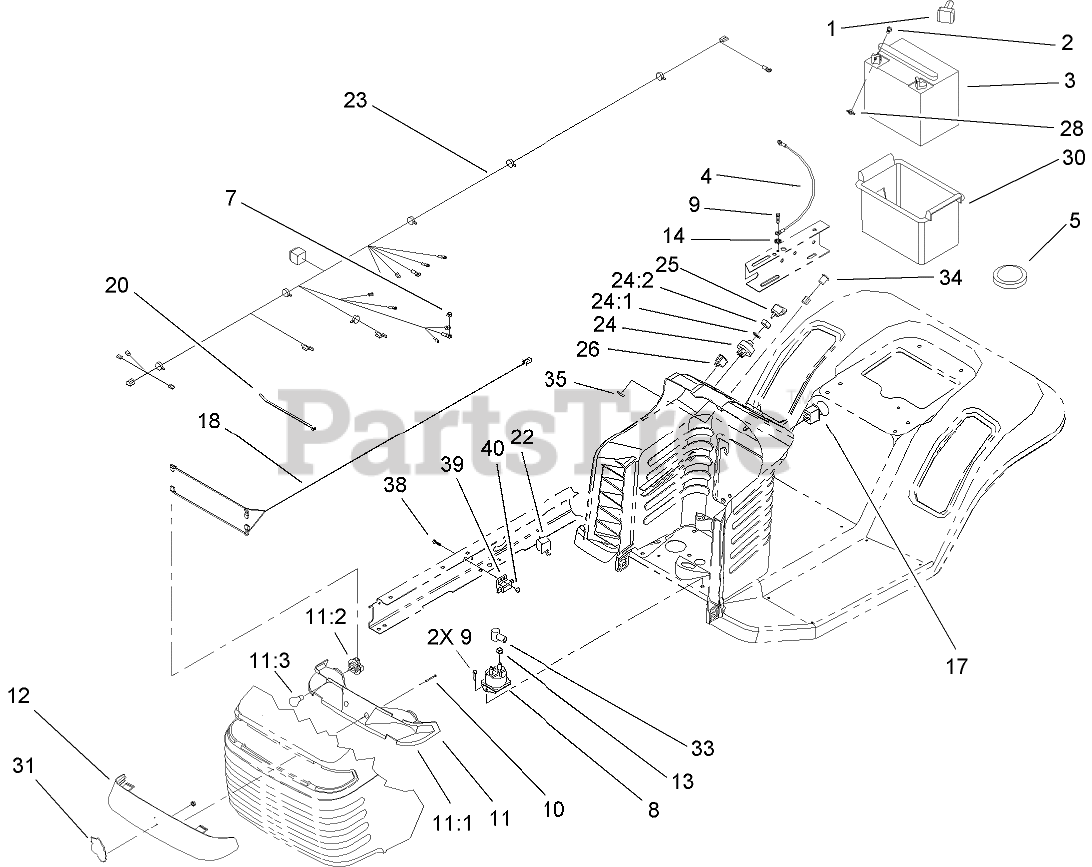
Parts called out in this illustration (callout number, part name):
1	BOOT-TERMINAL
2	SCREW-HH
3	BATTERY-155 CCA
4	WIRE ASM
5	SWITCH-SEAT
7	NUT-KEPS
8	SOLENOID-STARTER
9	SCREW-HWH
11	HEADLIGHT REFLECTOR ASM
11:1	REFLECTOR-LIGHT
11:2	SOCKET-HEADLIGHT
11:3	BULB
12	LENS-HEADLIGHT
13	NUT-KEPS
14	WASHER-LOCK/EXT
17	SWITCH-PTO
18	HARNESS-HEADLIGHT
20	TIE-CABLE
22	RELAY
23	HARNESS-WIRE
24	Key Switch ASM
24:1	WASHER-TOOTH, INTERNAL
24:2	NUT-HH
25	KEY-IGNITION
26	SWITCH-ROCKER
28	NUT-WING
30	BOX-BATTERY
31	EMBLEM
33	BOOT-INSULATOR, TERMINAL
34	LIGHT-INDICATOR
35	NUT-PUSH-ON, CIRCULAR
38	SCREW-HSH
39	SWITCH-POLE, SINGLE
40	NUT-LOCK, NI
